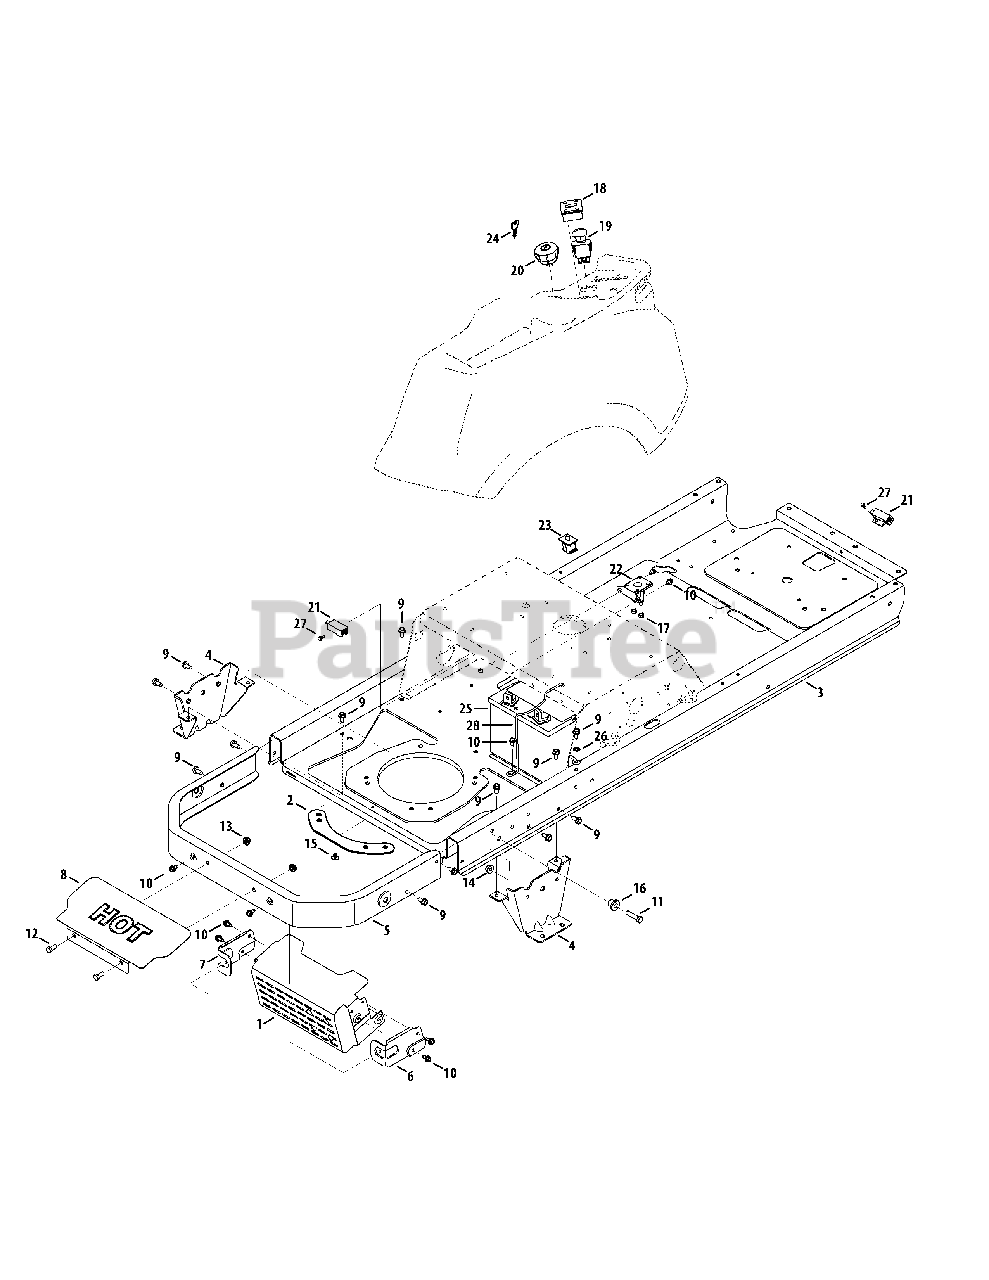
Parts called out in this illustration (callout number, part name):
1	Muffler Shield Assembly
2	Retainer Plate
3	Frame Assembly
4	Transmission Mounting Bracket
5	Rear Bumper
6	Muffler Mounting Shield Bracket, RH
7	Muffler Mounting Shield Bracket, LH
8	Muffler Shield
9	Hex Washer Screw, 5/16-18 x .750
10	Hex Washer Screw, 1/4-20 x .625
11	Hex Screw, 3/8-16 x 1.25
12	Hex Screw, 5/16-18 x .75
13	Flange Lock Nut, 5/16-18
14	Flange Lock Nut, 3/8-16
15	Clip, .250 Dia. x .500 LG
16	Shoulder Spacer, .38 x 1.0 x .70
17	Flange Lock Nut, 1/4-20
18	Hour Meter/Service Minder
19	Electric PTO Switch
20	Key Switch
21	Interlock Switch
22	Solenoid
23	Seat Switch
24	Universal Key Switch
26	Lock Washer, 5/16
27	Shoulder Screw, #10-32 x .500
